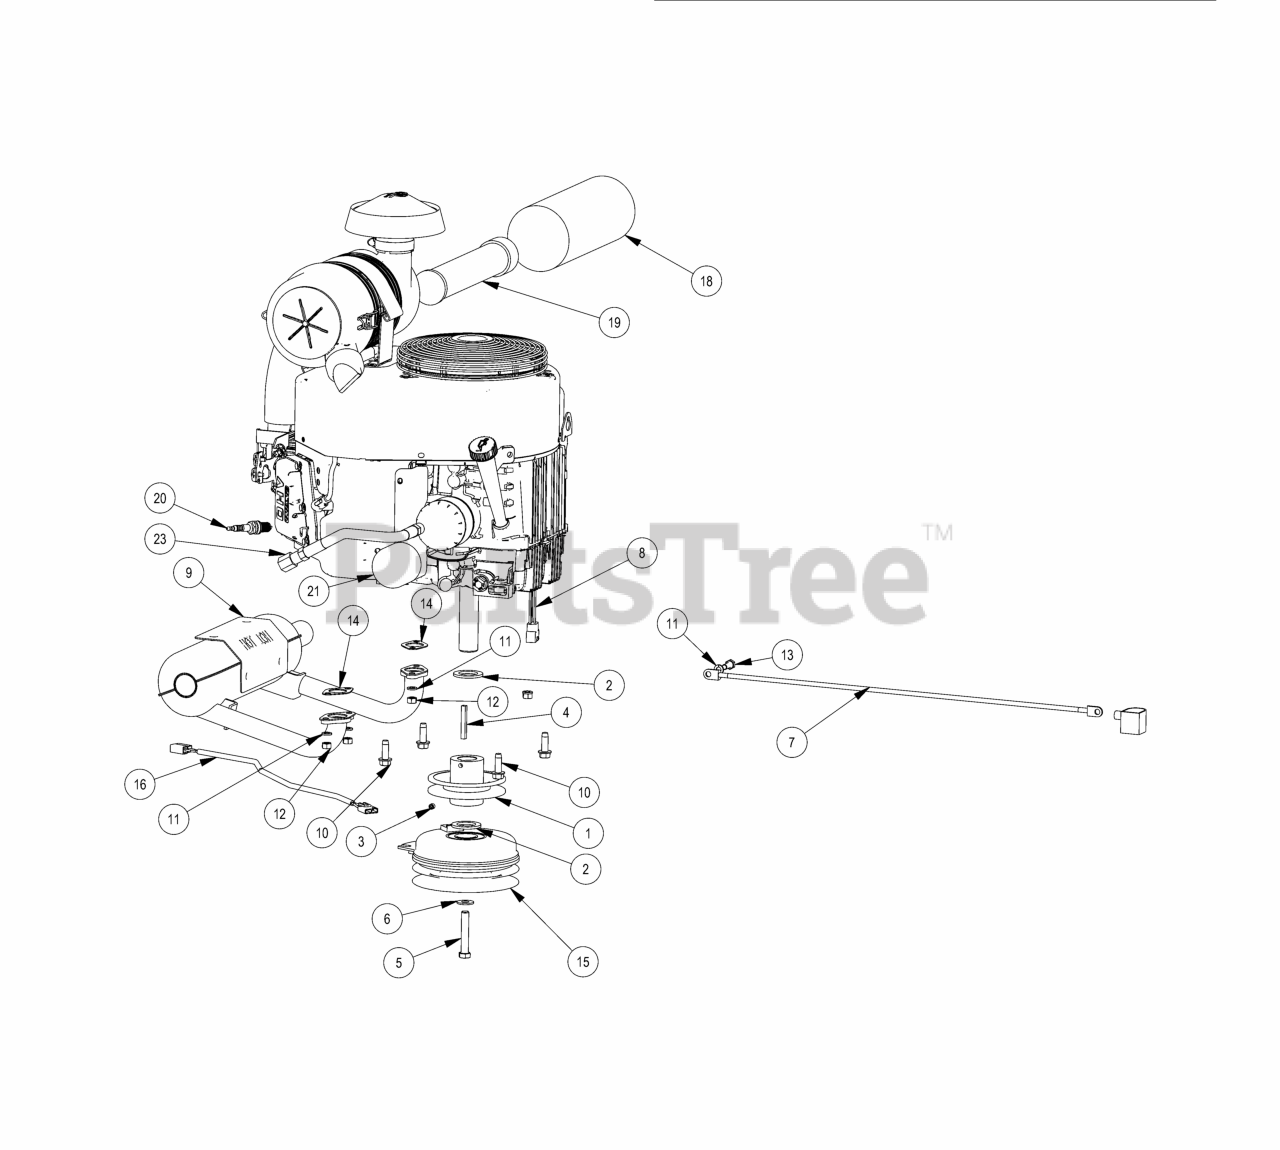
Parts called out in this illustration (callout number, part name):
1	4 3/4 Motor Pulley
2	1.140 ID X 1.750 OD X .132 THICK FLAT WASHER PLAIN
3	5/16-24 X 1/4 SOCKET SET SCREW (CUP PT) PLAIN
4	1/4 X 2 SQ MACHINERY KEY 1018 STL PLAIN
5	7/16-20 X 2-1/2 HEX CAP SCREW (GR.8) ZINC YELLOW
6	3/8 FLAT WASHER USS (1" OD) ZINC
7	24 inch Black Cable – MZ/ZT
8	2019 Harness Adaptor-Gen2 FX-ALL
9	Exhaust-Stand On-FX691V Kawasaki
10	3/8-16 X 1-1/8 HEX WASHER UNSLOT SERRATED (TRI-LOB) TRS ZINC YELLOW
11	5/16 SPLIT LOCKWASHER ZINC
12	M8-1.25 DIN 934 HEX NUT (CL.8) ZINC
13	M8-1.25 X 20MM DIN 933 HEX TAP BOLT (CL 8.8) ZINC
14	Exhaust Gasket
15	Clutch Assembly
16	Clutch Pigtail
18	Canister Air Filter- Outer
19	Canister Air Filter- Inner
20	Spark Plug - Kawasaki
21	Oil Filter
23	Oil drain Hose
24	Engine FX730
